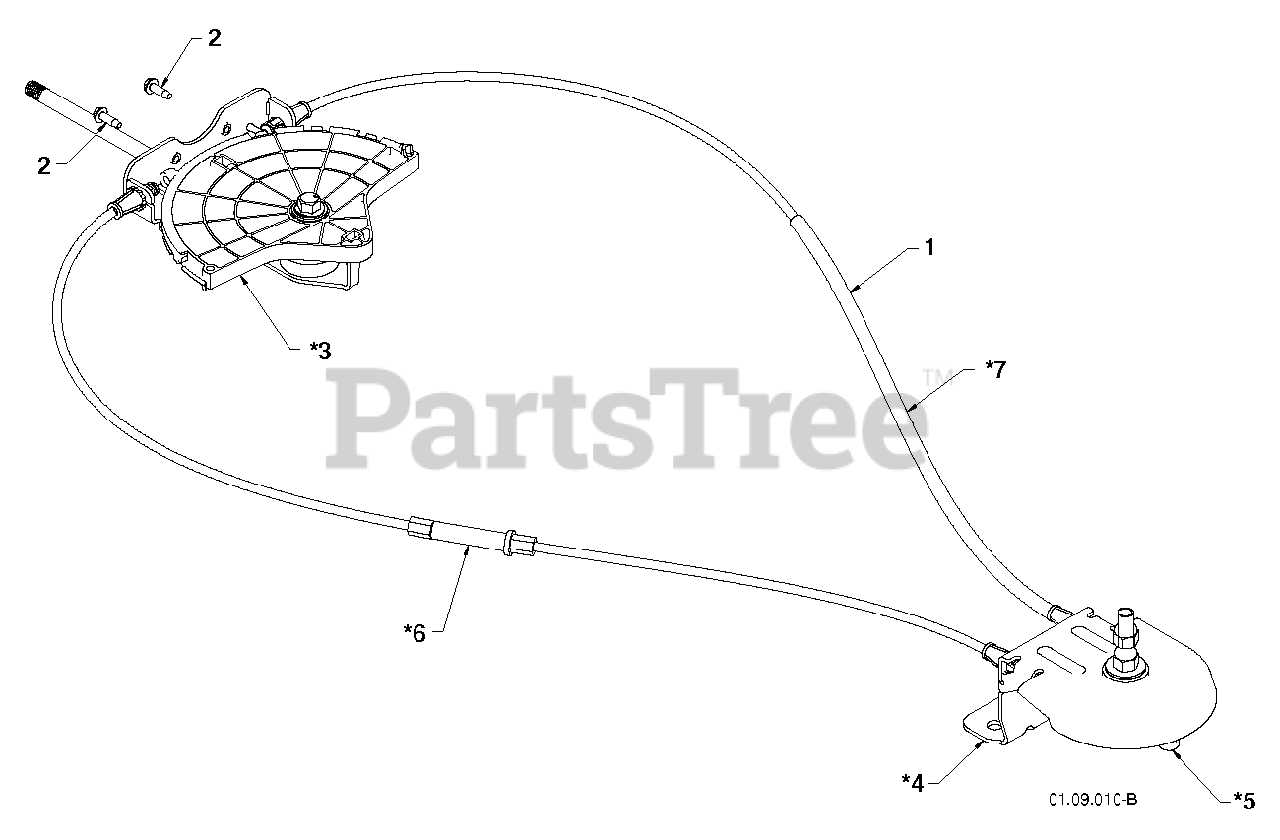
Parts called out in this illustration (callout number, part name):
1	LEVER/CABLE.ASM.ROTATOR
2	SCREW #10-24 X 5/8
3	CHUTE.ROT.HEAD.SERVICE
4	SNOW.PIVOT.BRKT.BLK.SERVICE
5	SNOW.PIVOT.PULLY
6	SNOW.CBL.ASM.ADJ.SERVICE(74)
7	SNOW.CBL.ASM.SERVICE(428272)
